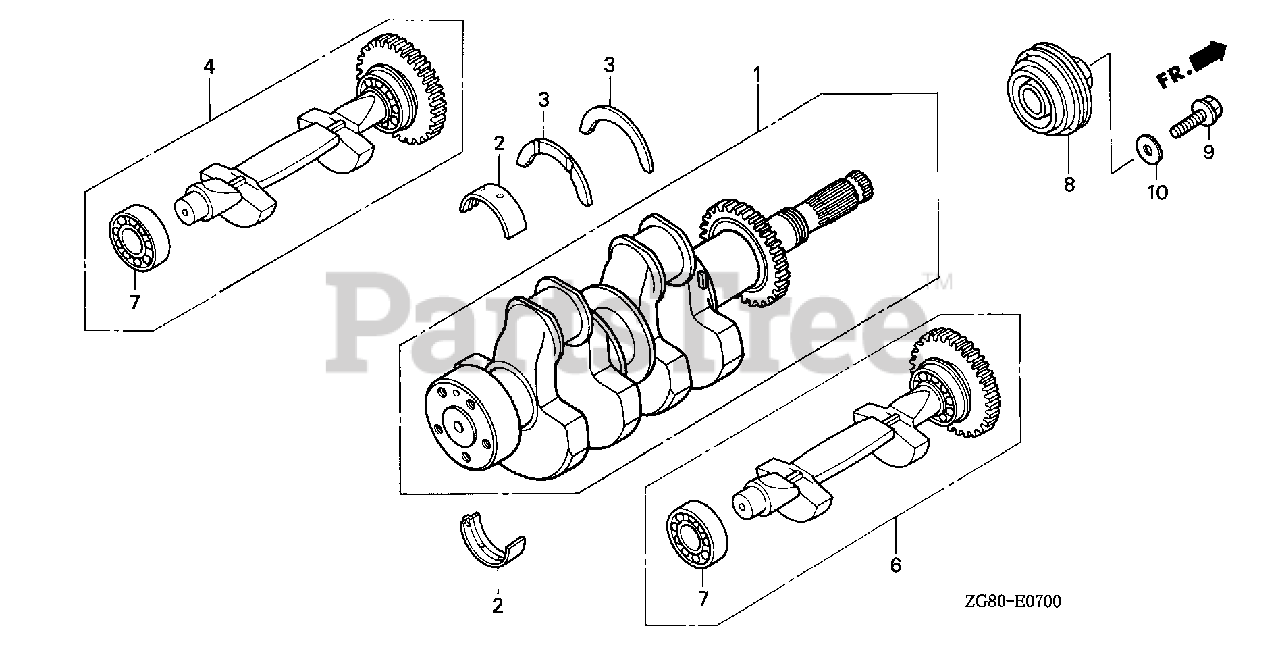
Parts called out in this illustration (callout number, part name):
1	CRANKSHAFT
2	BEARING A, MAIN (BLUE)
2	BEARING B, MAIN (BLACK)
2	BEARING C, MAIN (BROWN)
2	BEARING D, MAIN (GREEN)
2	BEARING E, MAIN (YELLOW)
2	BEARING F, MAIN (PINK)
2	BEARING G, MAIN (RED)
3	WASHER, THRUST
4	WEIGHT, R. BALANCER
6	WEIGHT, L. BALANCER
7	BEARING, RADIAL BALL (6203)
